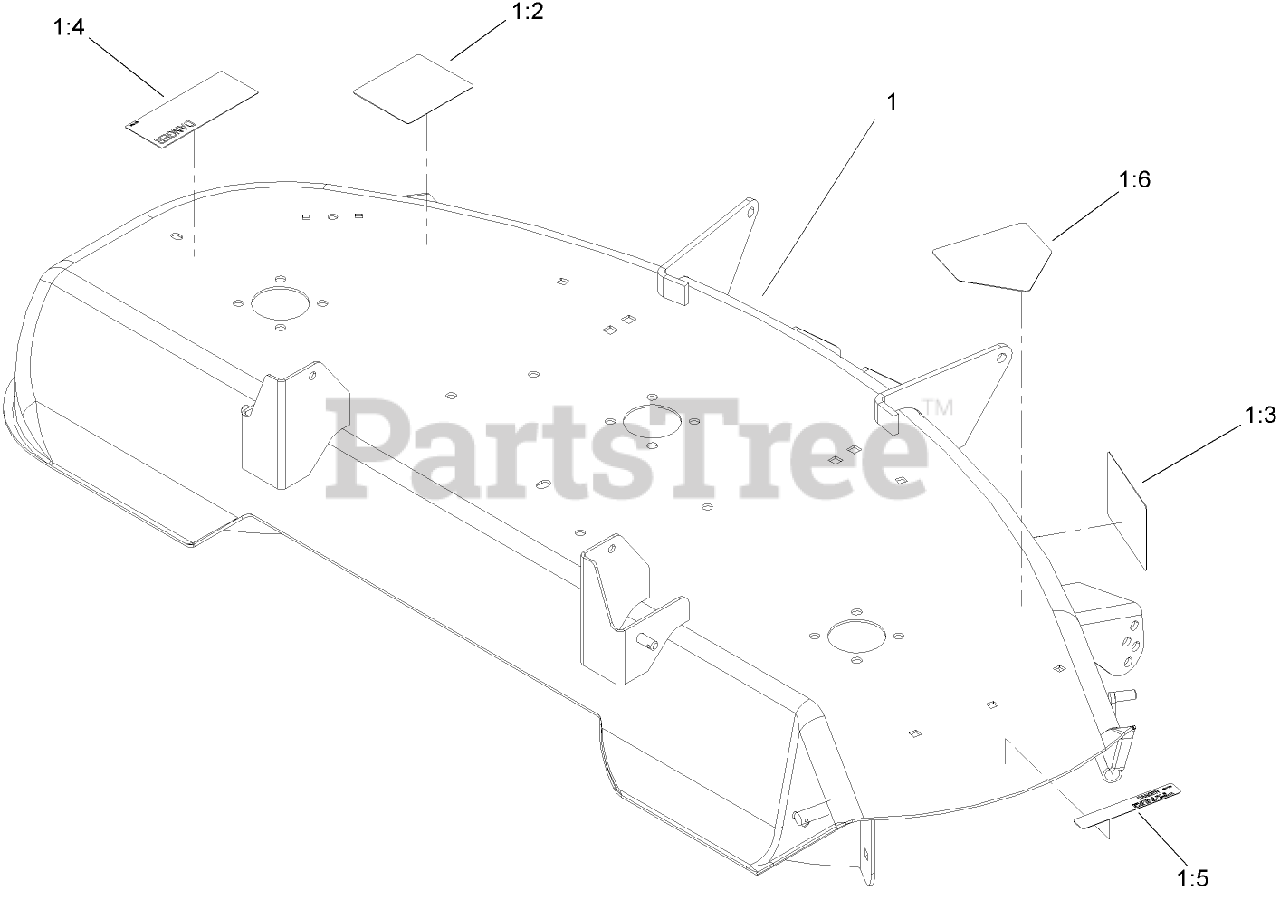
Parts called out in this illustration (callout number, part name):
1	Loose Parts Package
1:2	DECAL-ROUTING, BELT
1:3	DECAL-WHEEL, GAGE
1:4	DECAL-DANGER
1:5	DECAL-CAUTION
1:6	DECAL-DANGER
